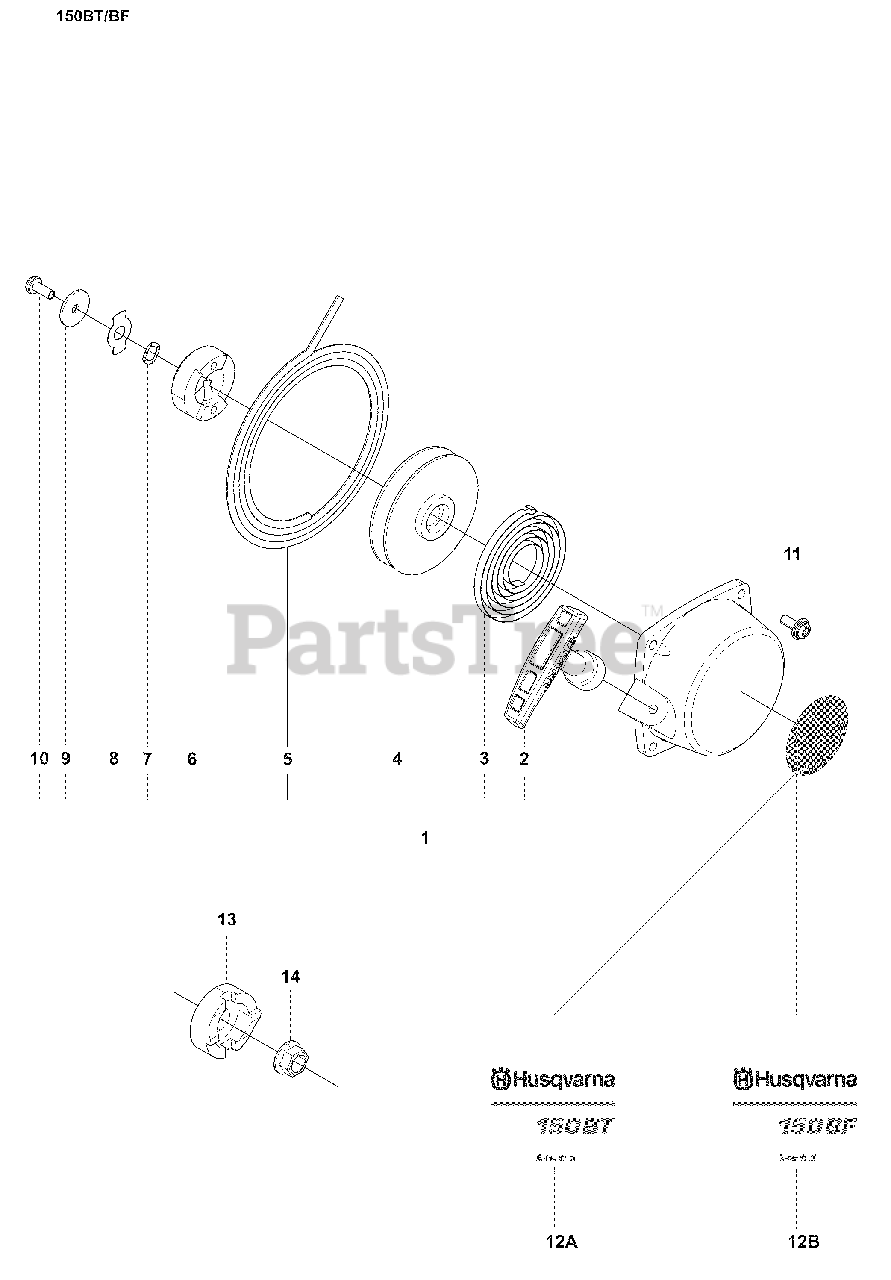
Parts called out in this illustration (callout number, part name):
1	STARTER ASSY
4	STARTER PULLEY
6	STARTER PAWL
8	RETAINER
9	WASHER
12A	DECAL
12B	DECAL
13	STARTER PAWL
14	NUT
